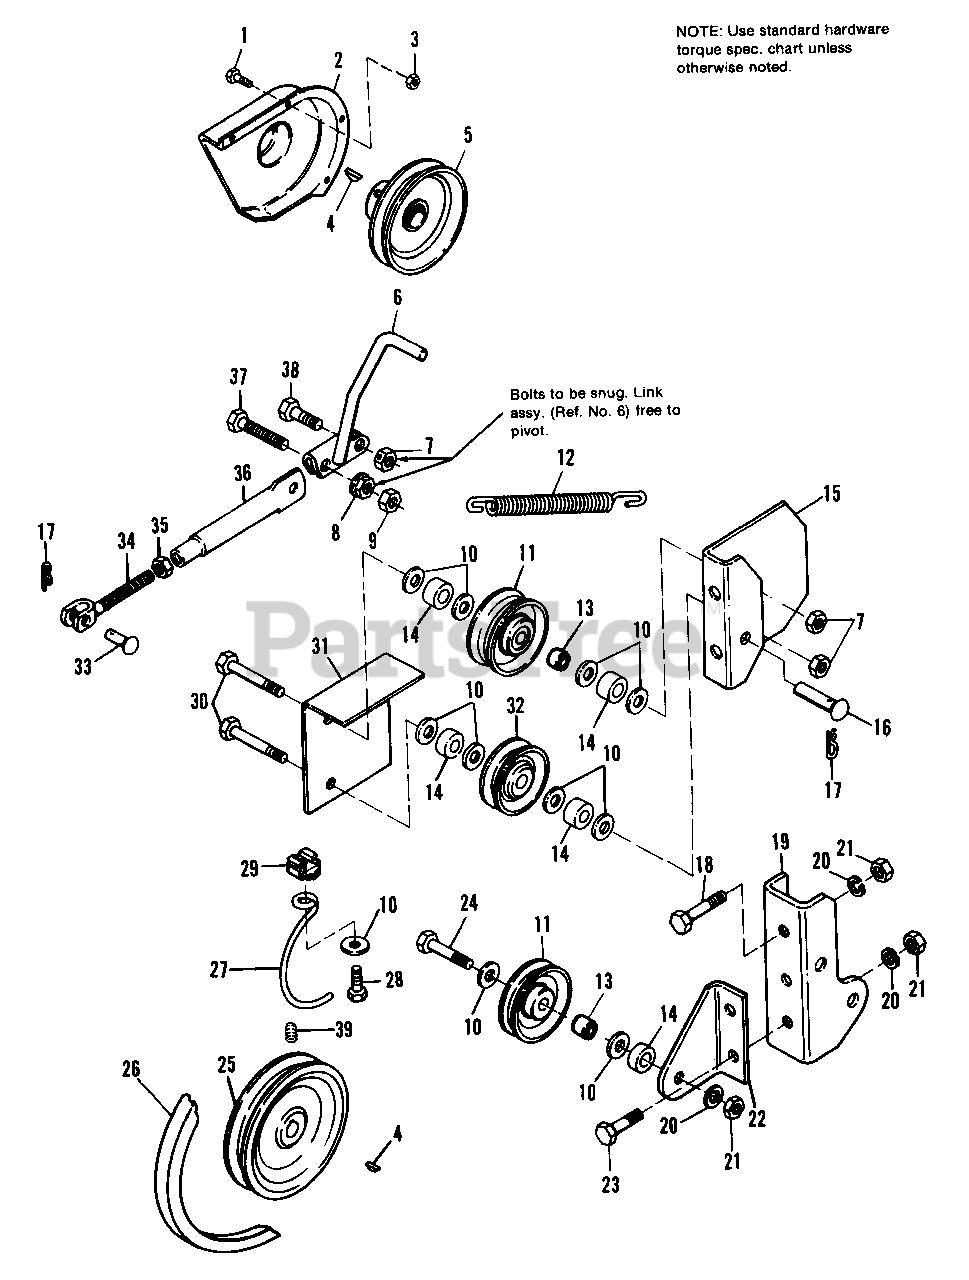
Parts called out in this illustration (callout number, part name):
1	CAPSCREW, Hex, 1/4-20 x 1/2
2	GUARD, Belt, Pulley
3	LOCKNUT, Hex, Full, 1/4-20
4	KEY, Woodruff, #9, 3/16 x 3/4
5	PULLEY (Driven)
6	LEVER ASSY., Clutch
7	LOCKNUT, Hex, Full, 3/8-16
8	LOCKNUT, Hex, Full, 3/8-16
9	LOCKNUT, Hex, Half, 3/8-16
10	WASHER, Plain, 5/16
11	PULLEY ASSY.
15	SUPPORT, Pulley
17	PIN, Quick
18	CAPSCREW, Hex, 3/8-16 x 3/4
19	BRACKET, Pulley Support
20	LOCKWASHER, 3/8
21	NUT, Hex, Full, 3/8-16
22	BRACKET, Pulley
23	CAPSCREW, Hex, 3/8-16 x 7/8
24	CAPSCREW, 3/8-16 x 1-1/2
25	PULLEY (Driver)
26	V-BELT (Drive)
27	STOP, Belt
28	SCREW, Whizlock, 5/16-18 x 3/4
29	NUT, Retainer, Tinnerman, 5/16-18
30	CAPSCREW, Hex, 3/8-16 x 2
31	GUARD, Idler Pulley
32	PULLEY, Idler
33	PIN, Lock
34	CLEVIS ASSY., Adj.
35	NUT, Hex, Full, 7/16-14
36	LINK, Clutch
37	CAPSCREW, Hex, 3/8-16 x 1-3/4
38	CAPSCREW, Hex, 3/8-16 x 1
39	SETSCREW, Hex, Soc. Cup Pt., 5/16-18 x 1/2
